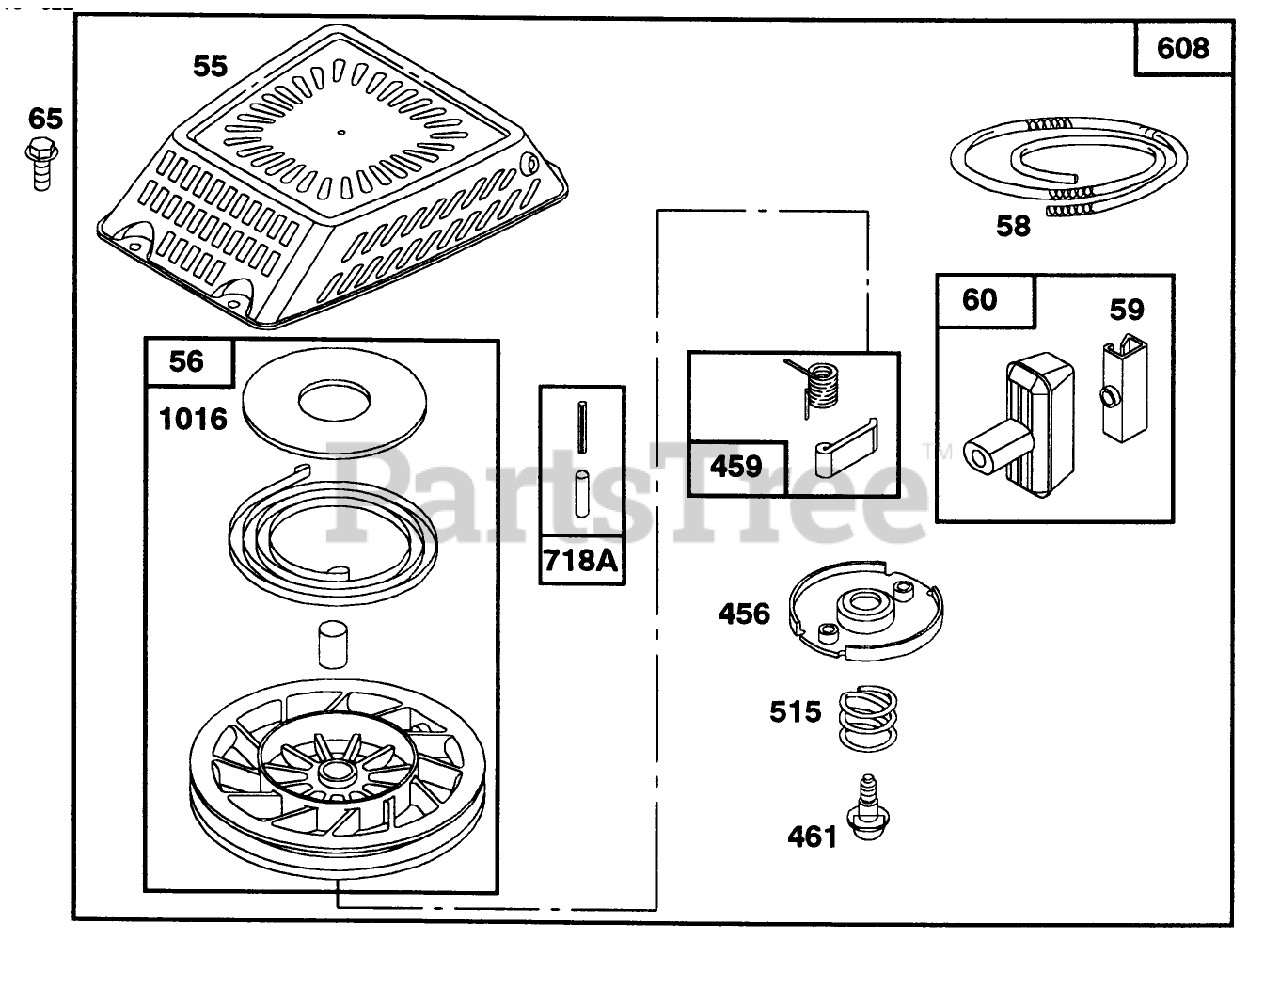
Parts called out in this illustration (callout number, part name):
59	INSERT-HANDLE, REWIND
456	RETAINER - SPRING
515	SPRING - RETAINER
